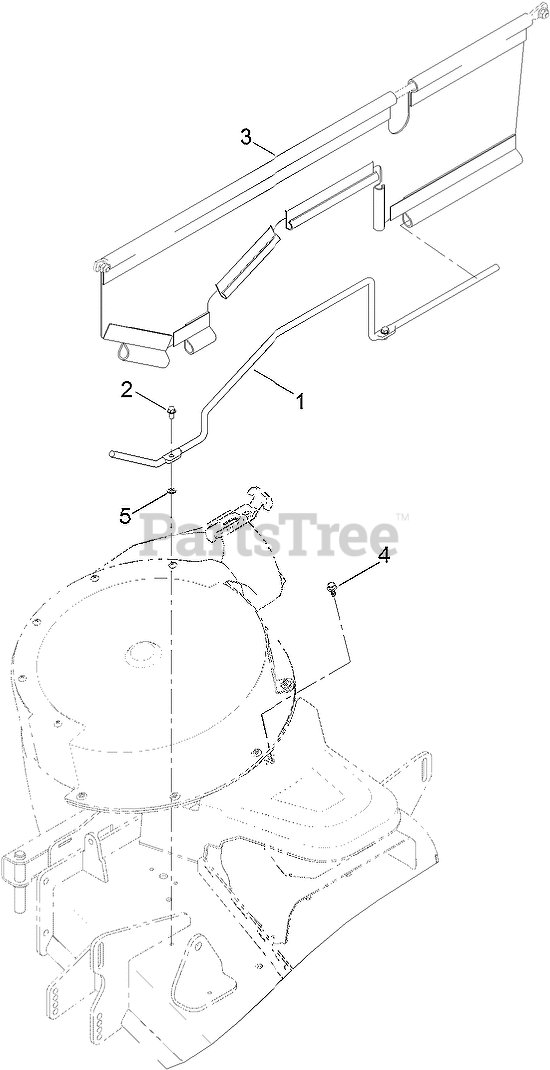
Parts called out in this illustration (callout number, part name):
1	ROD SUPPORT, LOWER
2	SCREW-HWH
3	GUARD-SIDE, POLY KNIT
4	SCREW-HHF
5	NUT-RETAINING
